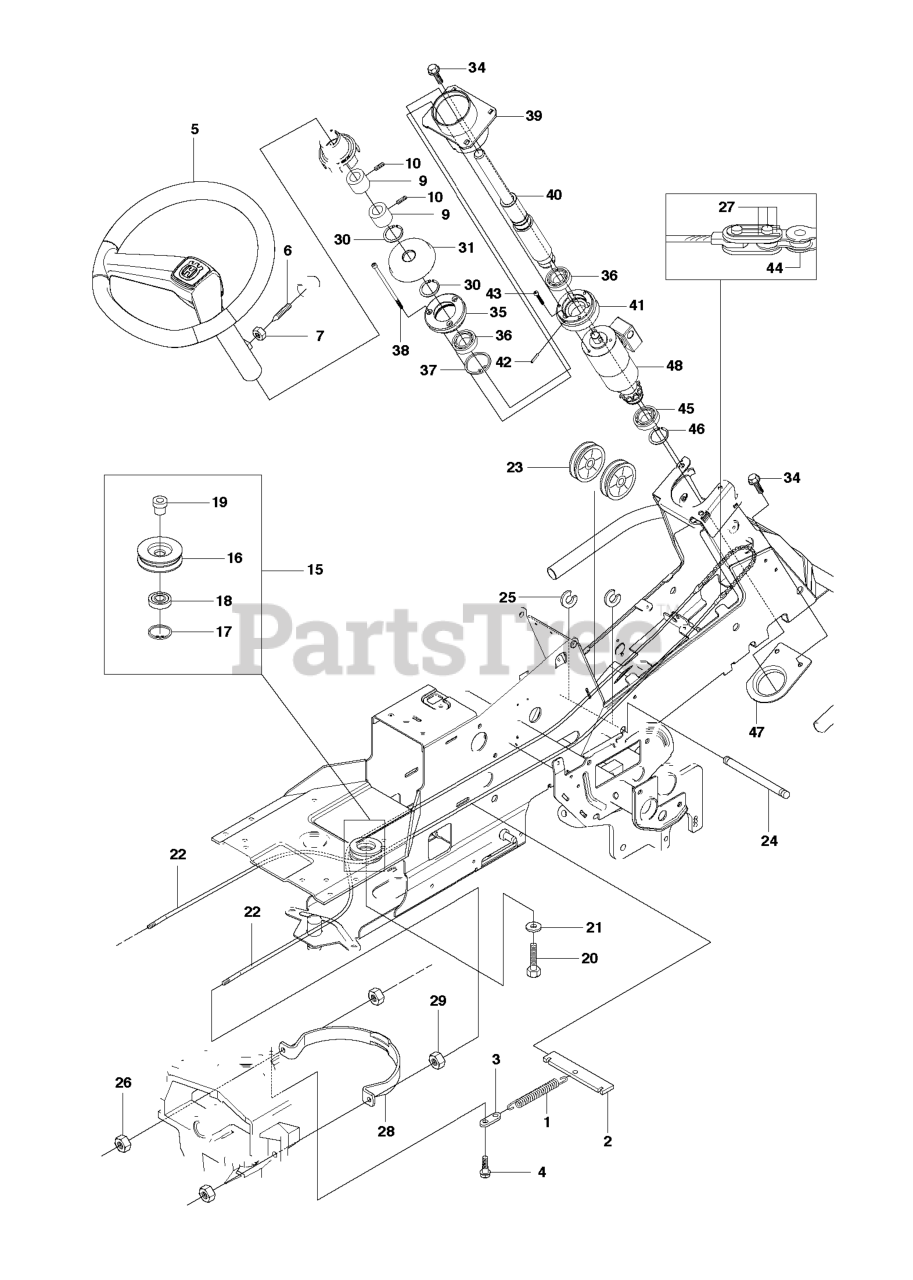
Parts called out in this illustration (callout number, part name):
2	SPRING BRACKET
7	NUT
9	SPACER
17	CIRCLIP SGH 47
18	BALL-BEARING 6204-2RS
20	COLLAR SCREW
22	RP STEERING CABLE COMPLETE
24	SHAFT
25	RETAINING RING
26	NUT
28	WIRE GUIDE
29	NUT
30	RETAINING RING SGA 25
36	Ball Bearing 6005-2rs
37	CIRCLIP SGH 47
38	SCREW IHSCM.
42	SPRING PIN
43	SCREW MC6S 6X20
48	COMFORT STEERING
